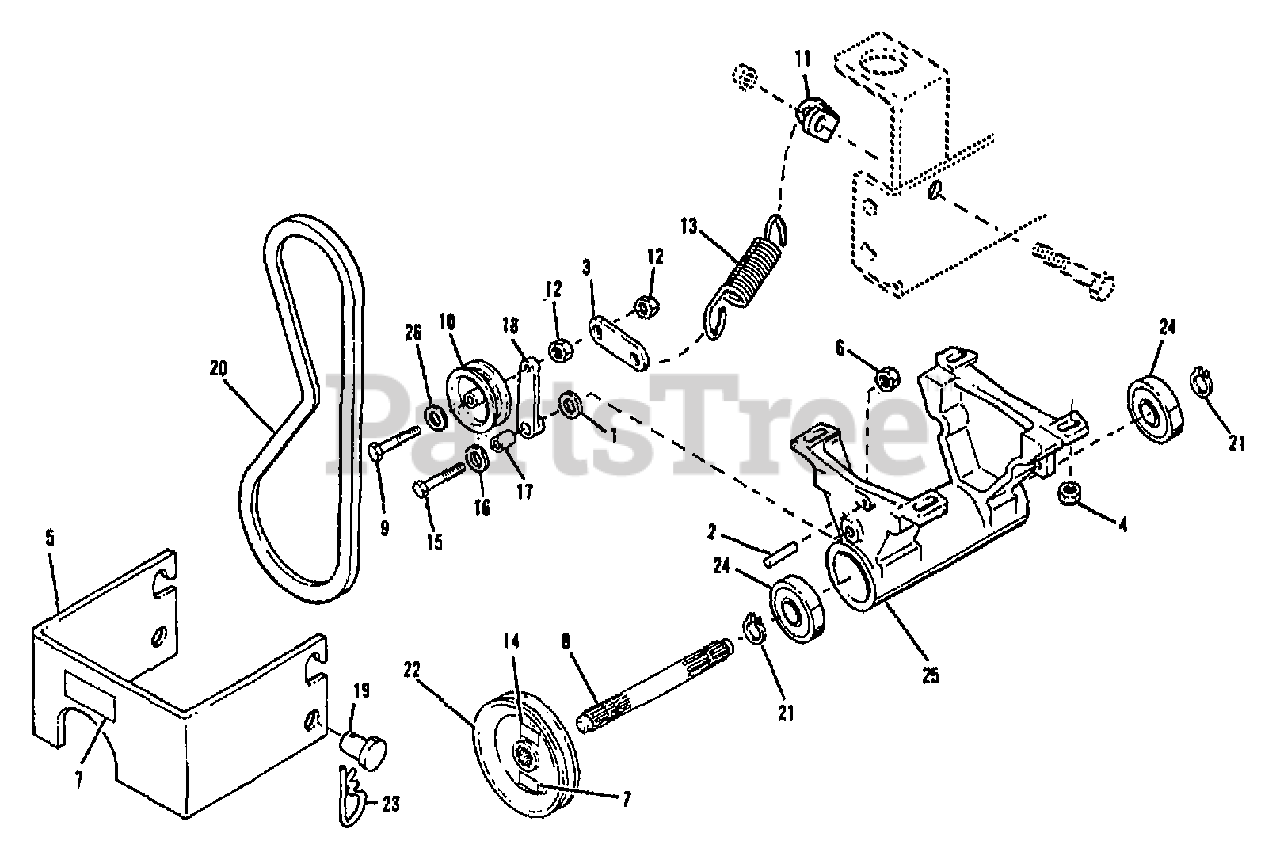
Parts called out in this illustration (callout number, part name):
1	WASHER-.88X.343X.1345
2	PIN-DRIVE .25X1.5
4	NUT-HF/LK 3/8-16
5	COVER-PTO
6	NUT-TOP/LK 5/16-18 ZP
7	DECAL-CAUTION
8	SHAFT-PTO
9	SCR-HH 3/8-16X2.0 G5 ZP
10	IDLER-FLAT
12	NUT-HEX/JAM 3/8-16 ZP
13	SPRING-EXT
14	DECAL-INST
15	SCR-HH 5/16-18X2.00
16	WASHER-FLAT 5/16 SAE
19	PIN-CLEVIS .5X1.06 ZP
20	BELT-V
21	RING-HEAVY EXT HD 1.0 ID
23	PIN-HITCH .125X2.56 ZP
24	BEARING-BALL
26	WASHER-FLAT 3/8 SAE
26	PAINT-RED SPRAYCAN POWDER
